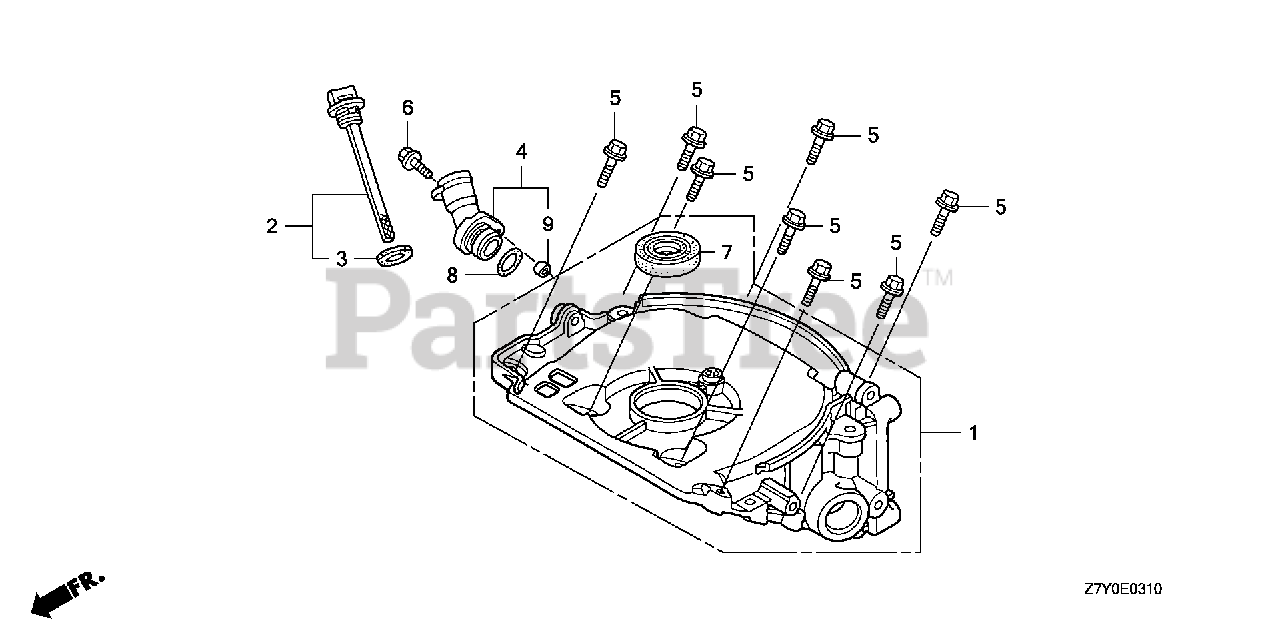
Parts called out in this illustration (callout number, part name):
1	CASE ASSY., OIL
2	CAP ASSY., OIL FILLER
3	GASKET, OIL FILLER CAP
4	EXTENSION, OIL FILLER
5	BOLT, FLANGE (5X23)
6	BOLT, FLANGE (5X14)
7	OIL SEAL (17X27X5) (KOYO)
8	O-RING (21.2X2.4) (ARAI)
9	COLLAR, TOP COVER
